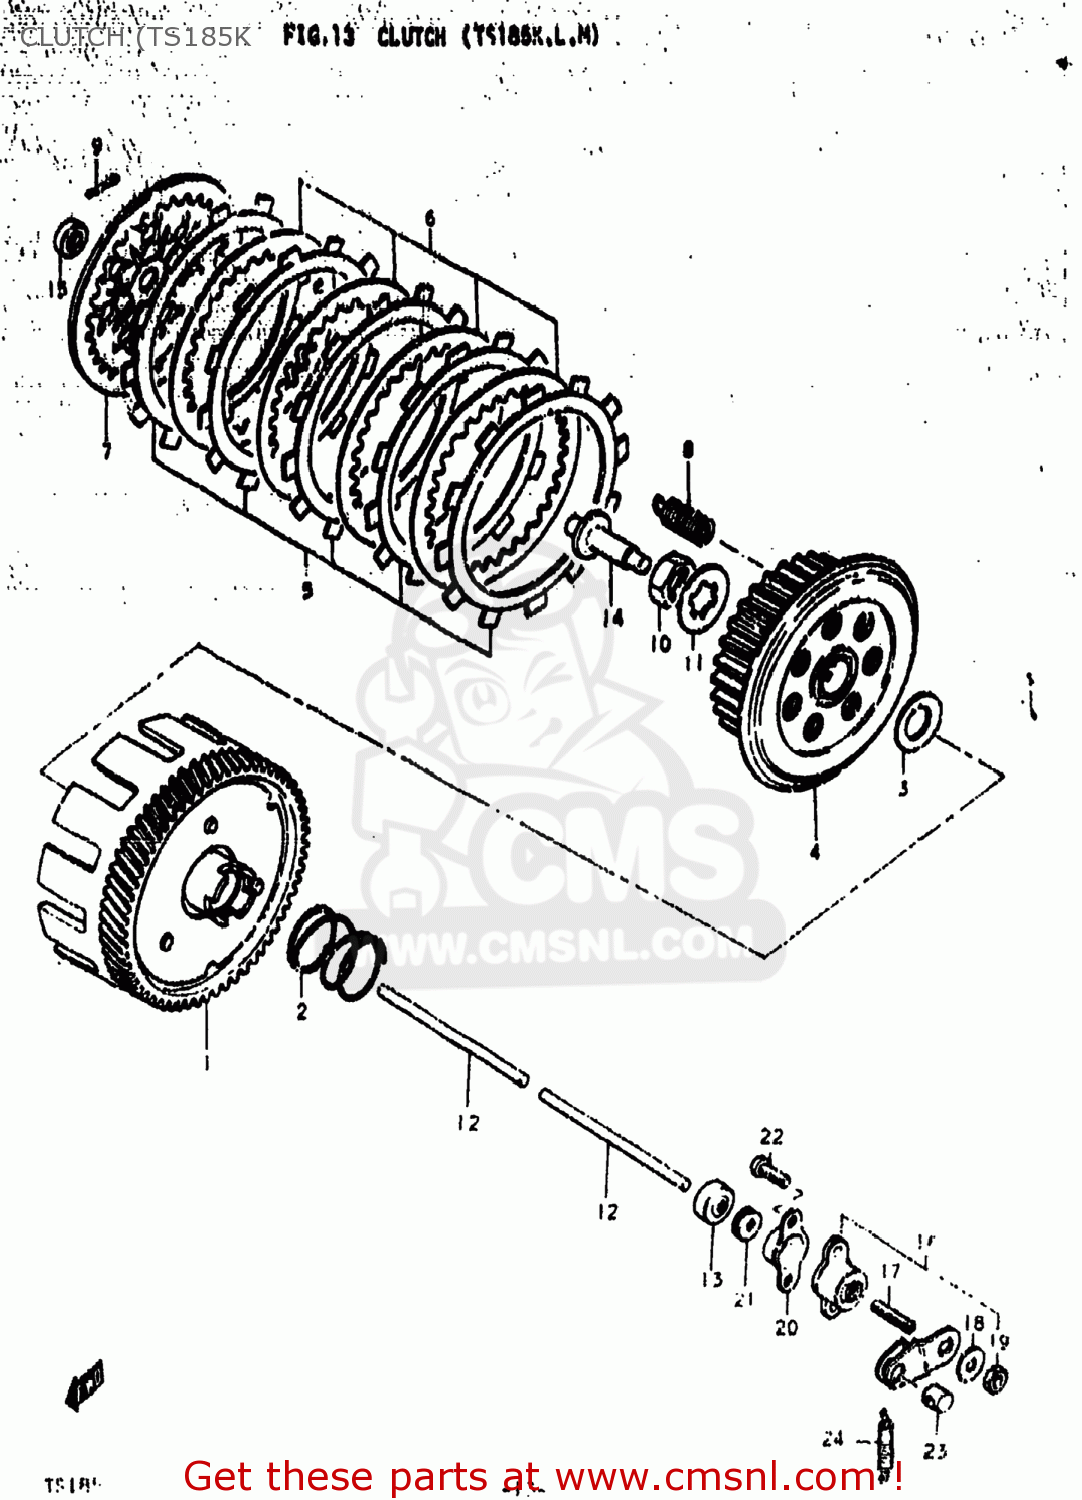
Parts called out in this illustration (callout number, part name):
1	GEAR ASSEMBLY,PRIMARY DRIVE
2	SPRING
3	WASHER
4	HUB,CLUTCH SLEEVE
5	PLATE,CLUTCH DRIVE
6	PLATE,CLUTCH DRIVEN (NAS)
7	PLATE,CLUTCH PRESSURE
8	SPRING
9	PIN(2.5X19.8)
10	NUT
11	WASHER,LOCK
12	ROD,CLUTCH PUSH
13	OIL SEAL
14	ROD,CLUTCH RELEASE
15	OIL SEAL
16	SCREW ASSEMBLY,CLUTCH RELEASE
17	SCREW
18	WASHER(6.5X16X1.2)
19	NUT
20	COVER,CLUTCH RELEASE SCREW
21	SEAL,DUST(5.3X13X5)
22	SCREW
23	PIECE,RELEASE ARM END
24	SPRING
